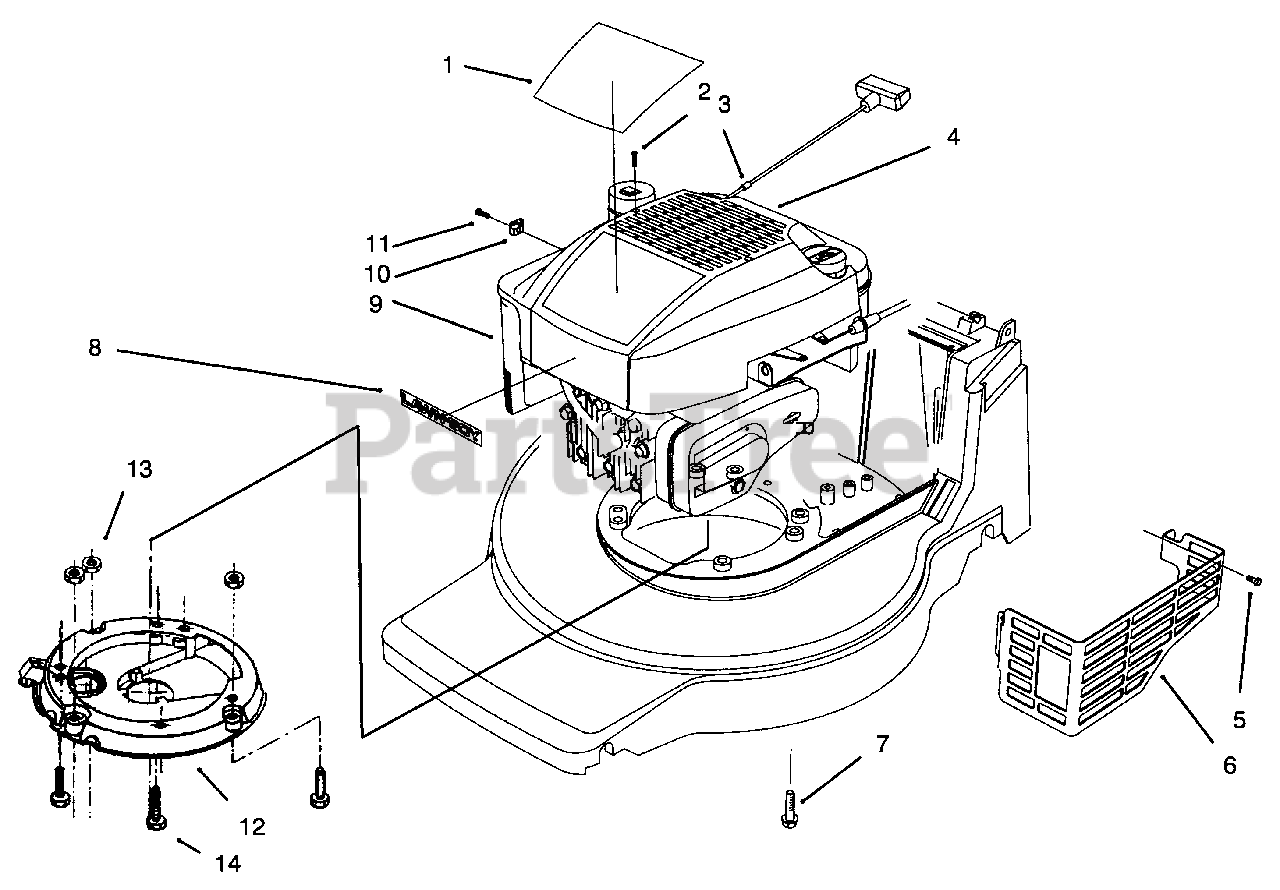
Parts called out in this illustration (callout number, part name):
1	Decal-Recoil
2	Screw-Mounting
3	Stop-Rope
4	Cover-XTE
5	Screw-Hex Washer Head Thread Forming
6	Shield-Muffler
7	Screw-Tapping
8	Decal-Shroud
9	Engine
10	Clamp-Casing
11	Screw-Clamp
12	Plate-Engine Mount
13	Nut-Lock
14	Screw-Hex Hd. Cap
